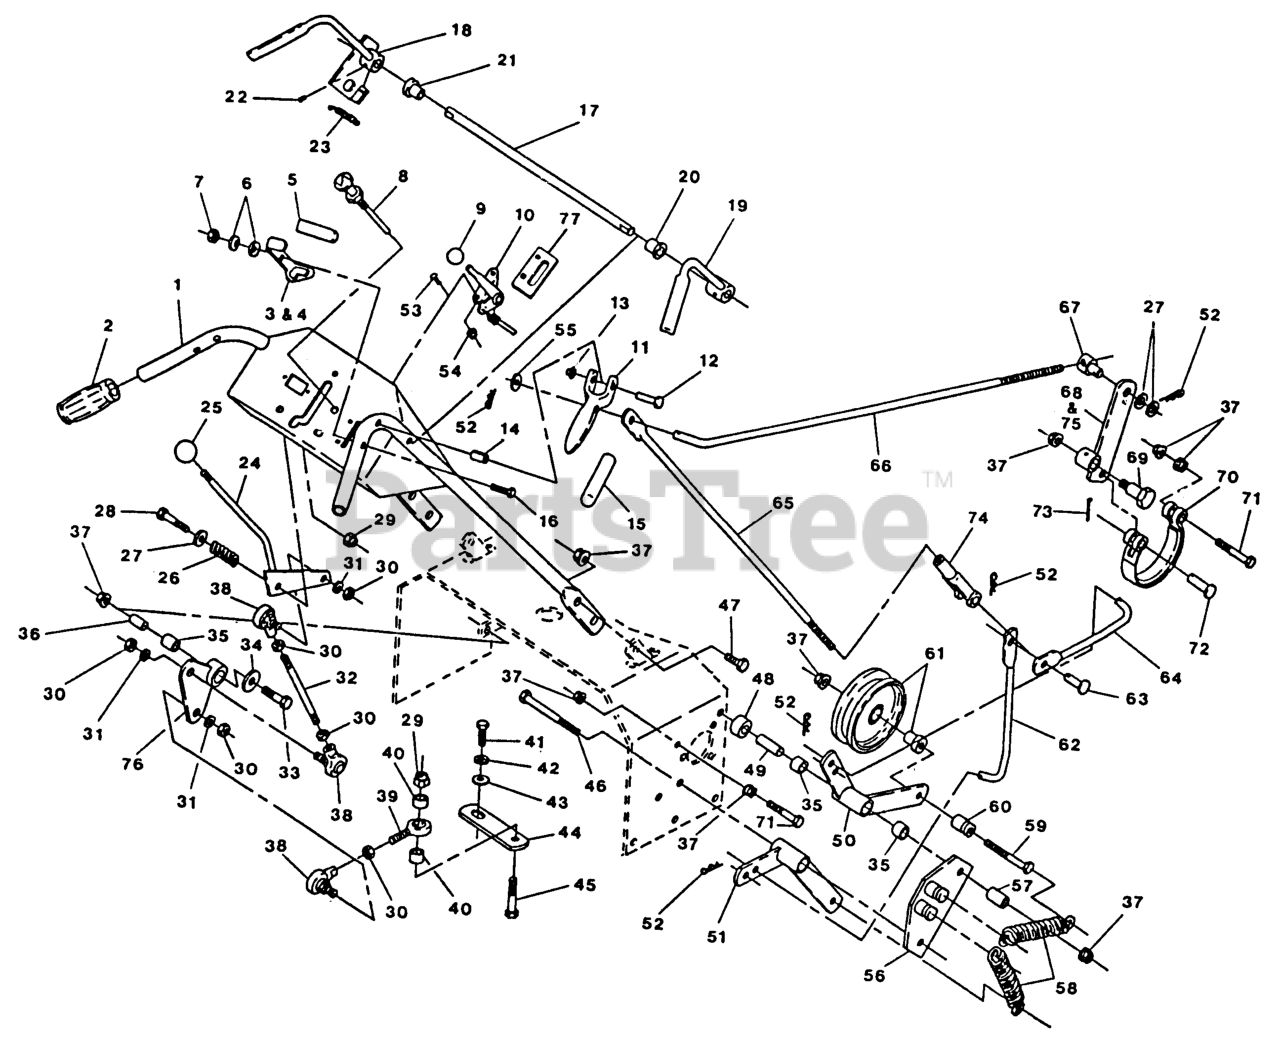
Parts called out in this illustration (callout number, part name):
5	GRIP-LATCH
6	WASHER-SPRING
7	NUTTORQUE ZNKPLT
8	CONTROL-CHOKE
9	KNOB-BALL
12	PIN-LEVER, DRIVE
13	NUT-PUSH
14	PIN-ROLL
15	GRIP-LEVER, DRIVE
17	ROD,CONNECTING
20	BUSHING-NYLON
21	BUSHING,FLANGED
23	SPRING-EXTENSION
25	KNOB-BALL
31	WASHER-LOCK
35	SLEEVE-BEARING
38	BALLJOINT
40	SPACER-PLATED
42	WASHER-LOCK
49	BUSHING-PIVOT, IDLER
52	PIN-COTTER
53	BOLT-CARR
58	SPRING-EXTENSION
60	ANCHOR-SPRING PLTD
61	KIT,48 RH IDLER/BUS
63	PIN-CLEVIS
66	LINKAGE,BRAKE
67	SWIVEL,SHORT ADJUSTING
69	BOLT-SHOULDER
74	YOKE-ADJUSTABLE
